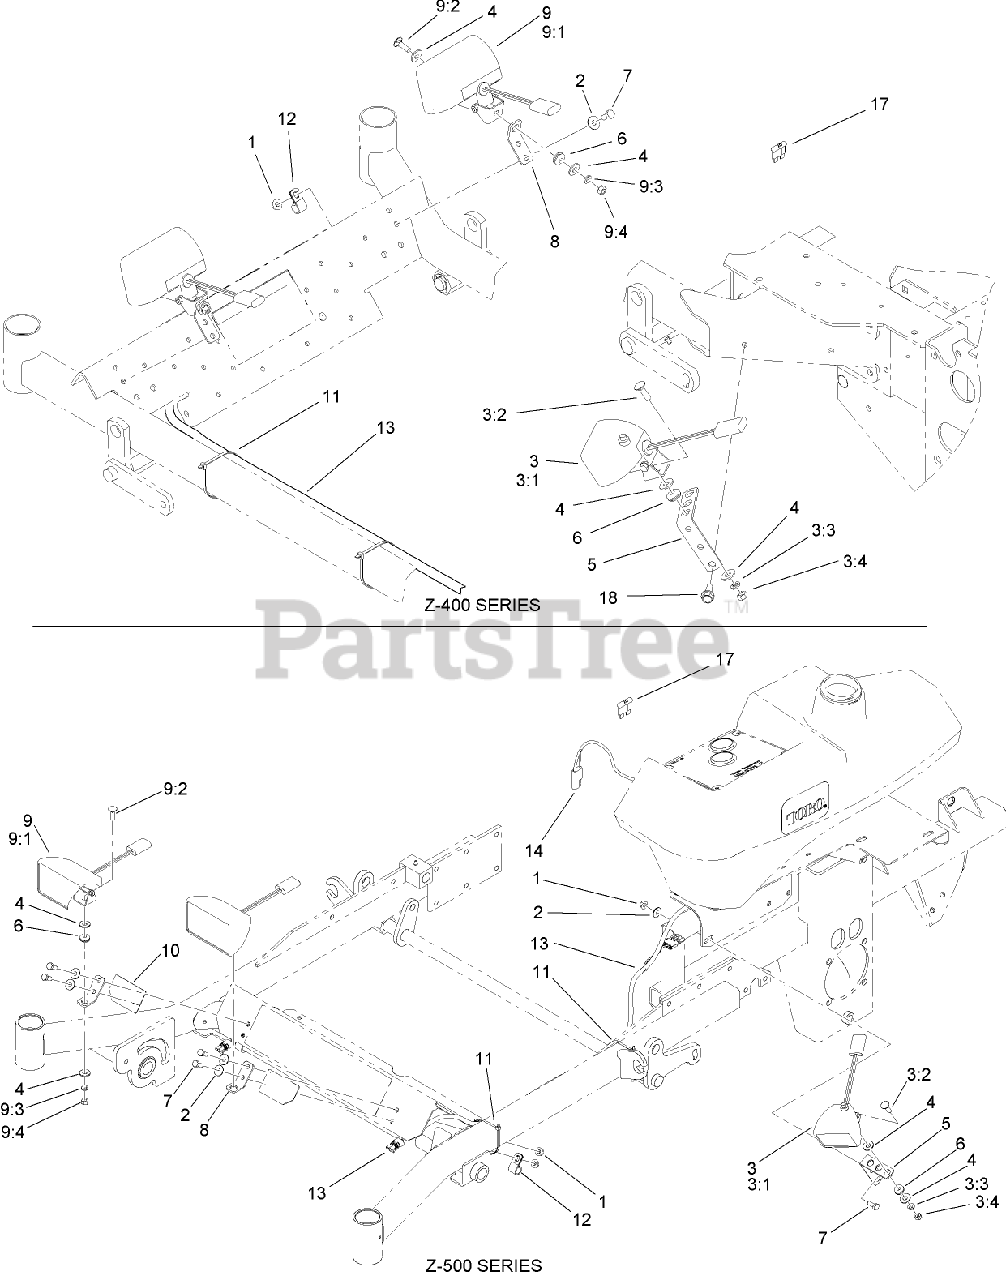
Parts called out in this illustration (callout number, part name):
1	NUT-HF
2	WASHER-BELLEVILLE
3	LAMP W/SWITCH
3:1	LAMP-12 VOLT
3:2	SCREW-CARR
3:3	WASHER-LOCK
3:4	NUT-HEX
4	WASHER-FLAT
5	BRACKET
6	GROMMET-RUBBER
7	SCREW-HH
8	BRACKET-MOUNT, LIGHT
9	LAMP ASM
9:1	LAMP-12 VOLT
9:2	SCREW-CARR
9:3	WASHER-LOCK
9:4	NUT-HEX
10	TEMPLATE-DRILL, FOOTREST
11	TIE-CABLE
12	CLIP-LOOM
13	HARNESS-ELECTRICAL
14	HARNESS-ELECTRICAL, DIESEL ADAPTER
17	FUSE-BLADE, 20 AMP
18	SCREW-HH, TAP
